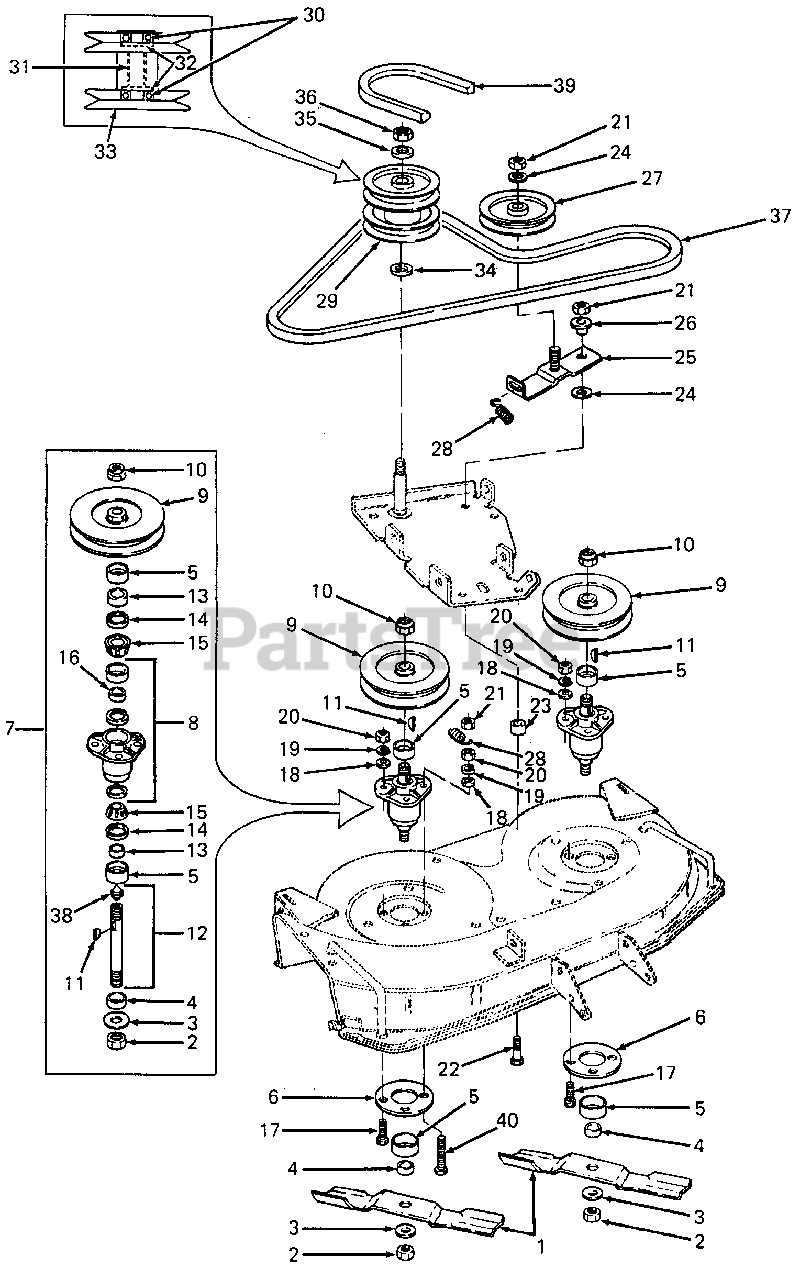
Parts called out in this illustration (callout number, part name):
1	Blade, Low Lift, 19.38 Lg
2	Nut, Hex, 3/4-16 GR8
3	Washer, Flat, .781 X 2.0 X .105 Thk HDN
4	Spacer, Blade
5	Cup, Spindle HDN
6	Plate, Spindle Mounting
7	Spindle Service Kit
8	Housing, Spindle w/Cups
9	4L V-Pulley, 4.62 OD X .75 ID
10	Nut, Hex Jam, 3/4-16
11	Key, #91 Woodruff, 1/4 X 3/4 HDN
12	Kit, Shaft w/Seal
13	Spacer, .755 X 1.25 X .44 Lg
14	Seal, Oil, 1.25 X 1.874 X .25
15	Cone, Bearing
16	Spacer, Bearing
17	Screw, Hex Cap, 3/8-16 X 1.25 GR5
18	Washer, Flat, .378 X 1.0 X .127 Thk
19	Washer, Lock, 3/8 Dia
20	Nut, Hex, 3/8-16 GR5
21	L-Nut, Hex Cent., 3/8-16 GR5
22	Bolt, Short Neck Carr, 3/8-16 X 1.5 Lg GR5
23	Spacer, .390/.400 ID X .75 OD X .44 Lg
24	Washer, Flat, .385 X .88 X .06 Thk HDN
25	Bracket, Idler
26	Spacer, Shld
27	Pulley, Flat Idler
28	Spring, Extension, .62 OD X 5.50 Lg
29	Pulley Assy, Double
30	Bearing, Ball, .62 ID X 1.38 OD X .44 Thk
31	Spacer, Pulley, .64 ID X .81 OD X 2.25 Lg
32	Snap Ring, Internal
33	Pulley, Double
34	Washer, Flat, .625 ID X 1.0 OD X .06 Thk HDN
35	Washer, Flat, .510 ID X 1.12 OD X .100 Thk
36	Nut, Hex Patch Jam, 1/2-20
37	V-Belt, 1/2 X 63" Lg - A Full
38	Fitting, Lube, 3/16
39	V-Belt, PTO Drive, 1/2 X 59.0
40	Screw, Hex Cap, 3/8-16 X 1.75 Lg GR5
